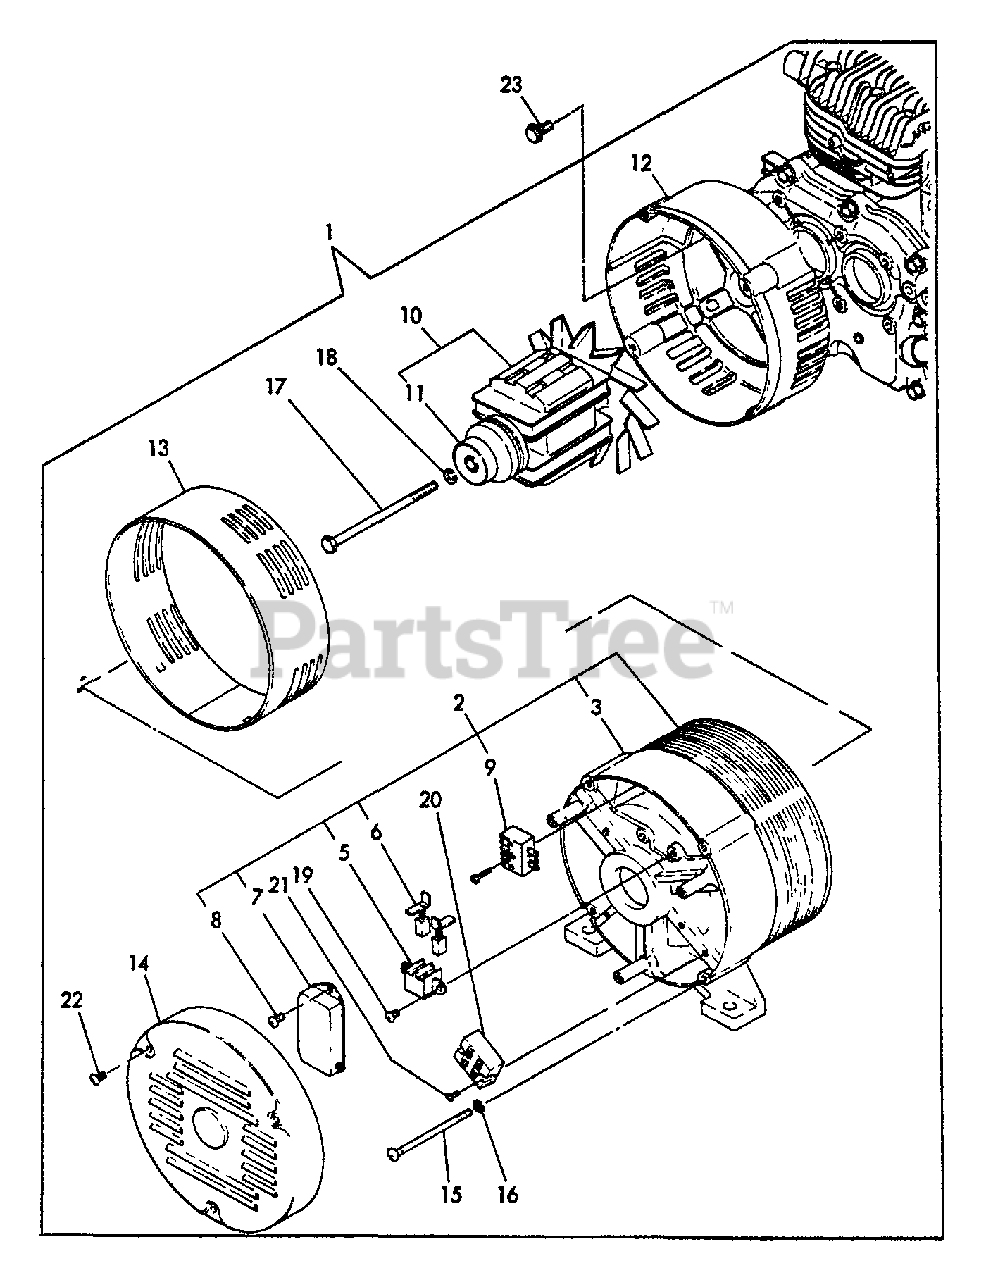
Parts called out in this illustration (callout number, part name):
1	GENERATOR 3.8KVA
2	STATOR ASSY
3	COVER - REAR
5	HOLDER, BRUSH
6	BRUSH ASSY
7	A.V.R.
8	SCREW - 4X14
9	RECTIFIER
10	ROTOR ASSY
11	BEARING, BALL
12	COVER - FRONT
13	CLAMP
14	COVER, END
15	BOLT, THROUGH
16	LOCKWASHER - 6
17	BOLT
18	LOCKWASHER - 10
19	SCREW - 5X14
20	TERMINAL
21	SCREW - 5X14
22	SCREW - 4X8
23	BOLT - 8X20 -- PLATED
